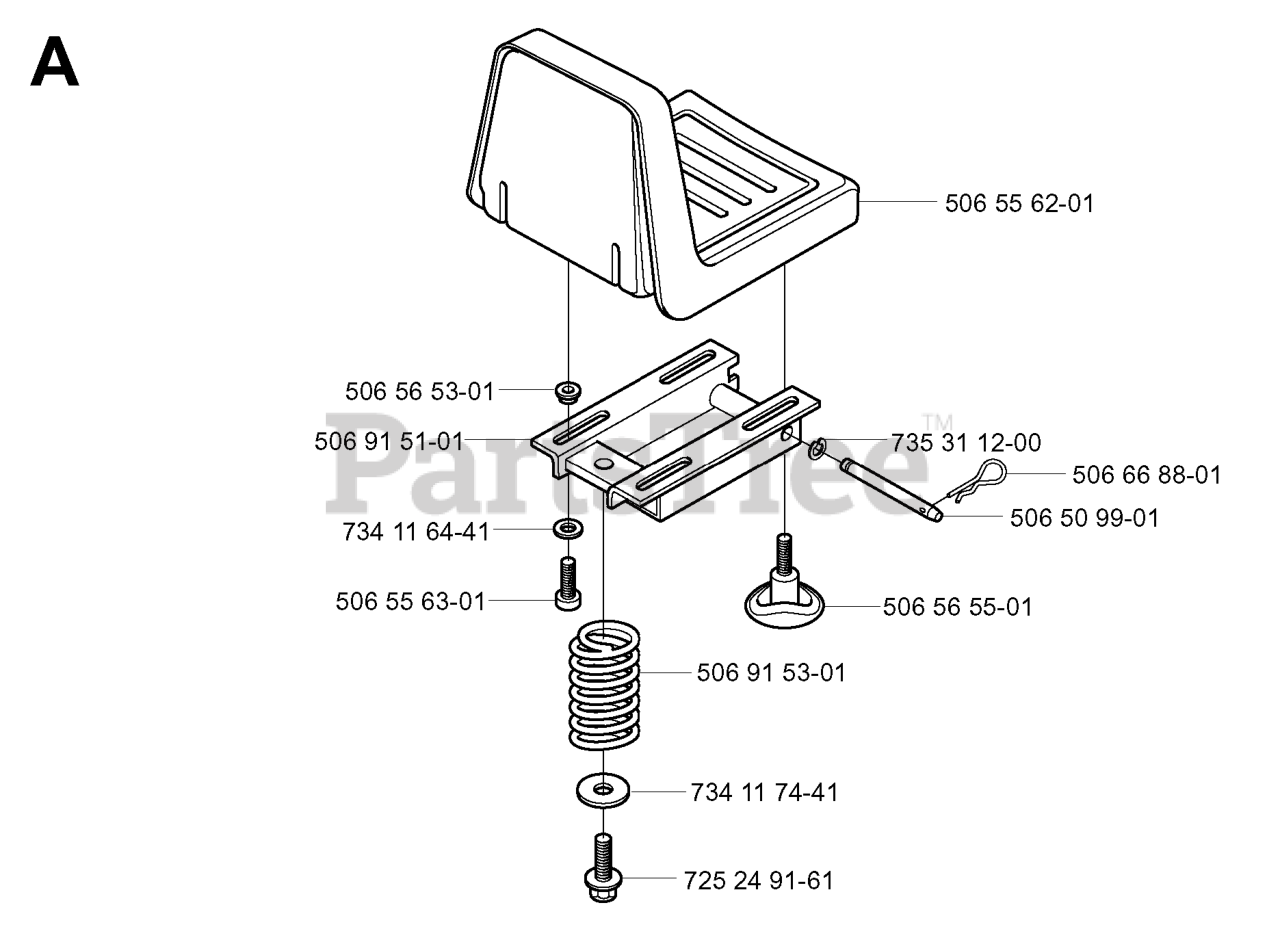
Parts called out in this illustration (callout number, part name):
80	PLATE, REAR MT RH
81	PLATE, REAR MT LH
82	SHIELD, ENGINE HEAT
83	SCREW, 1/4-20X.63
84	NUT 1/4-20
85	SCREW 5/16-18X.50
86	NUT, 5/16-18 REGHEXCTRLK
90	SUPPORT, FRAME
100	BRACKET, GAS TANK 2 CY
101	SCREW, #10-24X.63
110	TANK, FUEL, 1.62 QT.
112	CAP, FUEL, W/2654 SEAL
113	TUBING, GAS LINE 8 IN.
114	CLAMP, HOSE
115	FILTER, IN-LINE
116	TUBING, GAS LINE 3 IN.
117	CLAMP, TUBING
120	CLAMP, WORM DR
130	SHROUD, BOTTOM
131	SCREW, #10-24X.63
133	CLIP, "S" TINNERMAN
134	SCREW, 10-16X.50 DRILLITE
